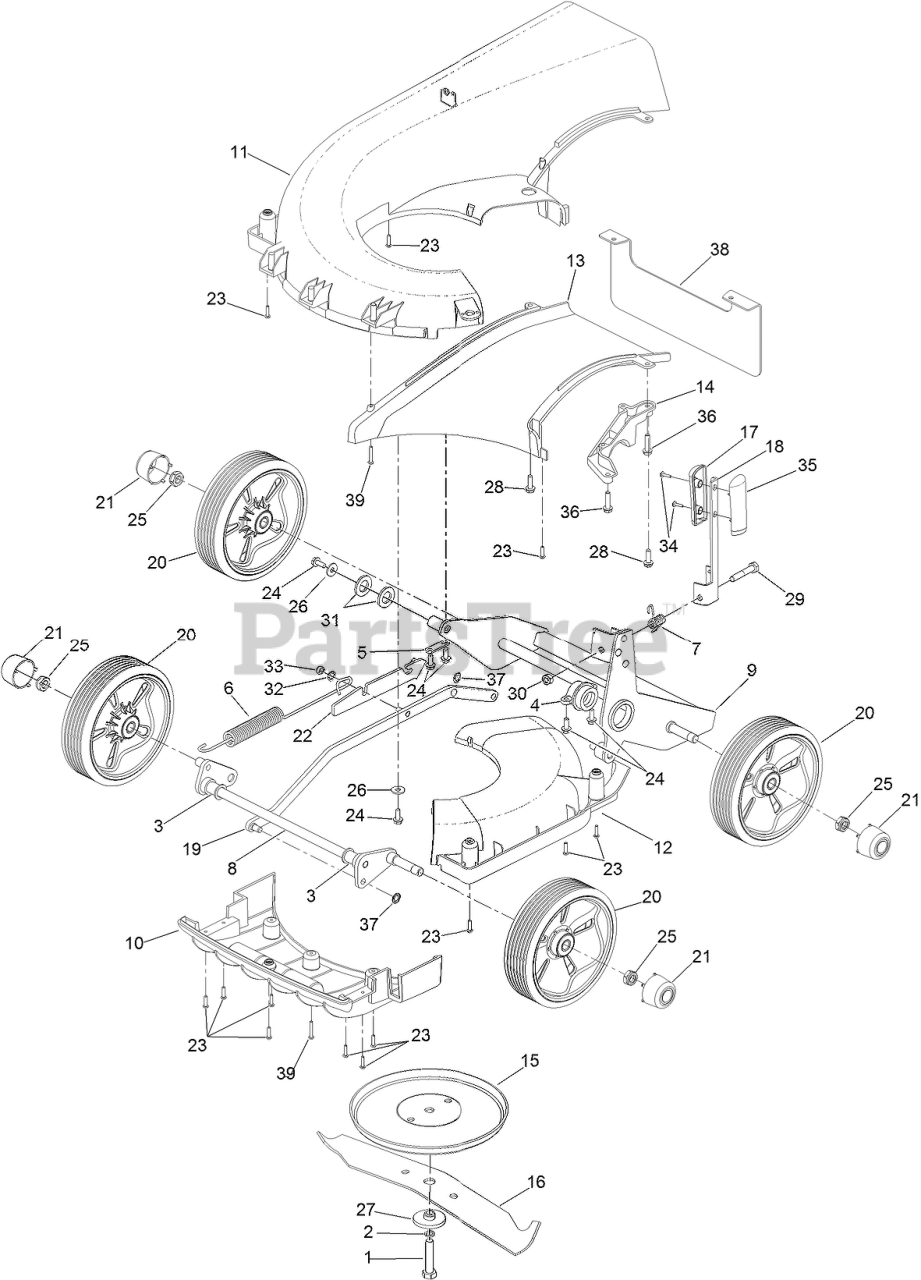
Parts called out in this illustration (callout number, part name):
1	BOLT-UNF
2	WASHER-SPRING
3	BEARING-AXLE, FRONT
4	HOUSING-PIVOT BEARING, LH
5	PLATE-SECURING
6	SPRING-COUNTER BALANCE
7	SPRING-HOC
8	AXLE-FRONT
9	FRAME-WHEEL
10	MOULDING-FIN
11	MOULDING-SNAIL DECK
12	MOULDING-ACCESS, SNAIL DECK
13	MOULDING-THROW PLATE
14	MOUNT-BEARING
15	DISC-FRICTION
16	CUTTERBAR
17	KNOB-HOC, RH
18	LEVER-HOC
19	ROD-CONNECTING BAR
20	WHEEL ASM
21	CAP-WHEEL, CENTER
22	MOUNT-SPRING
24	SCREW-TAPTITE
25	NUT-NYLOC
26	WASHER
27	SPACER-DISTANCE, CUTTERBAR
28	SCREW-TAPTITE
30	NUT-HEX, NI
31	WASHER-PLAIN
32	WASHER-PLAIN
33	NUT-NYLOC
35	KNOB-HOC, LH
36	SCREW-HH
37	WASHER-STARLOCK
38	GUARD-REAR
